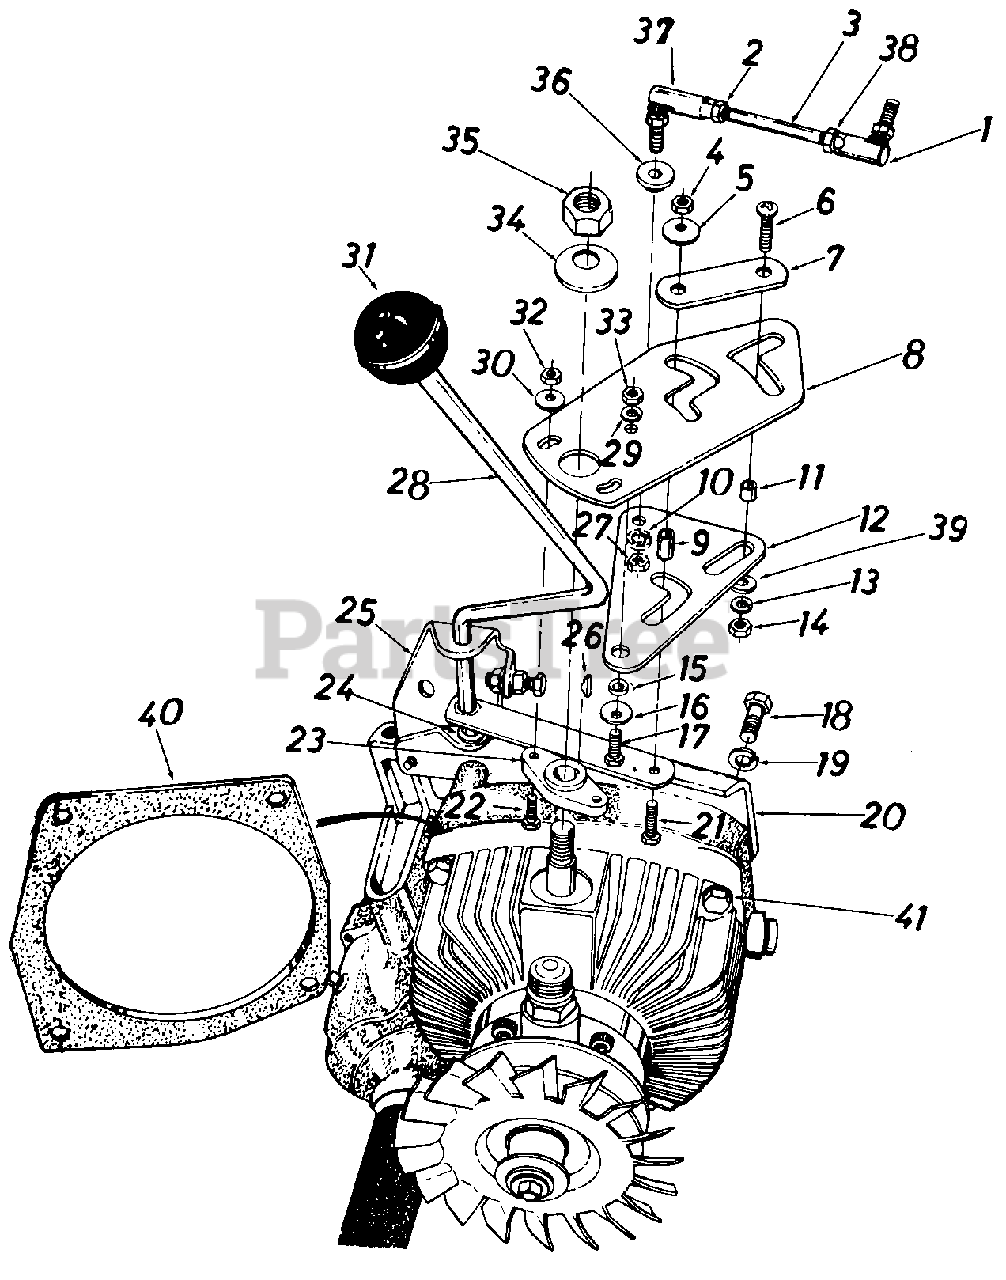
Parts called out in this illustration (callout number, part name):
1	Ball Joint Ass'y. 3/8-24 Thd.
2	Hex Nut 3/8-24 Thd.
3	Control Rod 3/8-24 x 3.75" Lg.
4	Hex Top L-Nut 3/8-24 Thd.
5	Fl-Wash. .385" I .D. x .87" O.D.
6	Truss Mach. Scr. Phil. 5/16-18 x 1.00" Lg.
7	Locking Link
8	Pintle Main Control Plate
9	Spacer.377" I.D. x .500" O.D. x .830" Lg.
10	L-Wash. 3/8" I.D.
11	Spacer.315" I.D. x .500" O.D. x .350
12	Pintle Drive Plate
13	L-Wash. 5/16" I.D.
14	Hex Nut 5/16-18 Thd.
15	Spacer .38" I.D. x .625 '
16	Bell-Wash. .39" I.D. x 1.13" O.D.
17	Hex Bolt 3/8-24 x 1.00" Lg.
18	Hex Bolt 3/8-16 x 1.0" Lg. Grade 5
19	L-Wash. 3/8" I.D.
20	Shift Lever Bracket
21	Hex Bolt 3/8-24 x 1.25" Lg.
22	Hex Bolt 1/4-28 x .75" Lg.
23	Pintle Hub
24	Nyliner.375" Dia. x .140
25	Shift Lever Bracket Upper
26	#5 Hi-Pro Key 1/8 x 5/8 Dia.
27	Hex Top L-Nut 3/8-24 Thd.
28	Shift Lever Assy.
29	L-Wash. 3/8 I.D.
30	Fl-Wash. .385" I.D. x .87" O.D.
31	Gear Shift Knob
32	Hex Nut 1/4-28 Thd.
33	Hex Top L-Nut 3/8-24 Thd.
34	Bell-Wash. .505" I.D. x 1.00" O.D.
35	Hex Nut 1/2-13 Thd.
36	Shld. Spacer.625" I.D.
37	Ball Joint Ass'y. 3/8-24 L.H.
38	Hex Jam Nut 3/8-24 Thd.
39	Fl-Wash. .33" I.D. x 1.25"
40	Gasket
41	Hex Bolt 2. 75" Lg.
